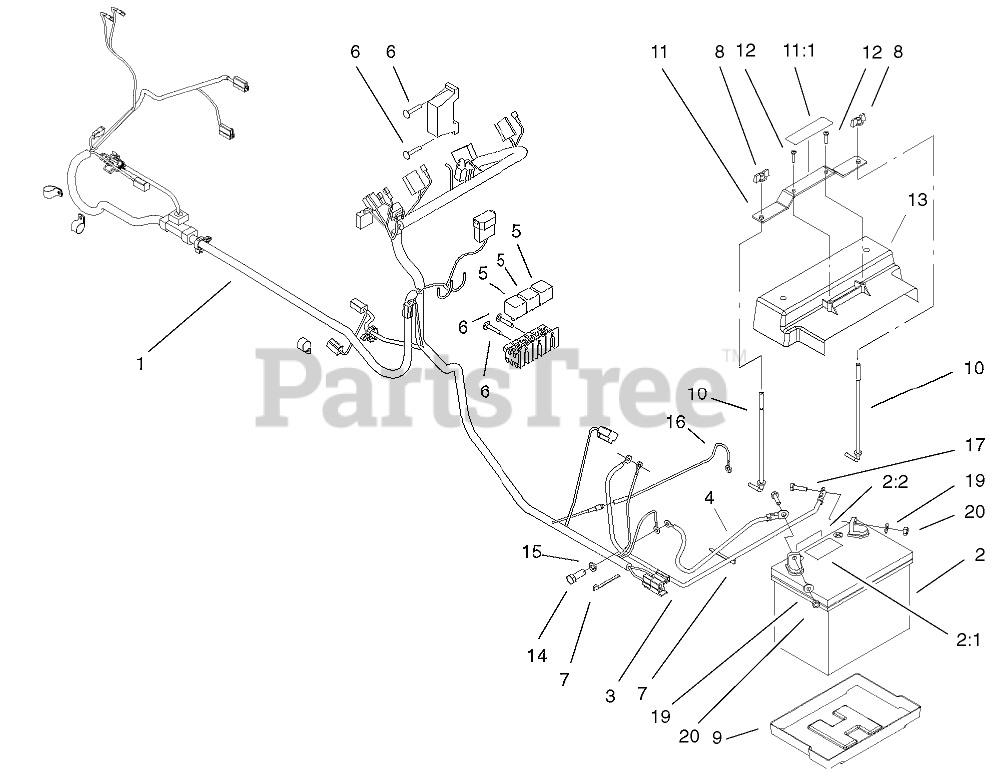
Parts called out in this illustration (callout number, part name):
1	Harness-Wire (only on: 73542, 73570)
2	Battery (only on: 73542, 73570)
2:1	Decal-Battery (only on: 73542, 73570)
2:2	Decal-Battery (only on: 73542, 73570)
3	Cable-Battery, Red 27" (only on: 73542, 73570)
4	Cable-Battery (only on: 73542, 73570)
5	Relay (only on: 73542, 73570)
6	Screw (only on: 73542, 73570)
7	Tie-Strap (only on: 73542, 73570)
8	Nut-Wing (only on: 73542, 73570)
9	Tray-Battery (only on: 73542, 73570)
10	Hook-Battery Retain (only on: 73542, 73570)
11	Strap ASM (only on: 73542, 73570)
11:1	Decal-Surface, Hot (only on: 73542, 73570)
12	Screw-PPH (only on: 73542, 73570)
13	Shield-Battery (only on: 73570)
13	Shield-Battery (only on: 73542)
14	Screw-HHF (only on: 73542, 73570)
15	Washer-Lock (only on: 73542, 73570)
16	Harness-Wire (only on: 73542, 73570)
17	Screw-HH (only on: 73542, 73570)
19	Washer-Flat (only on: 73542, 73570)
20	Nut-Lock, NI (only on: 73542, 73570)
